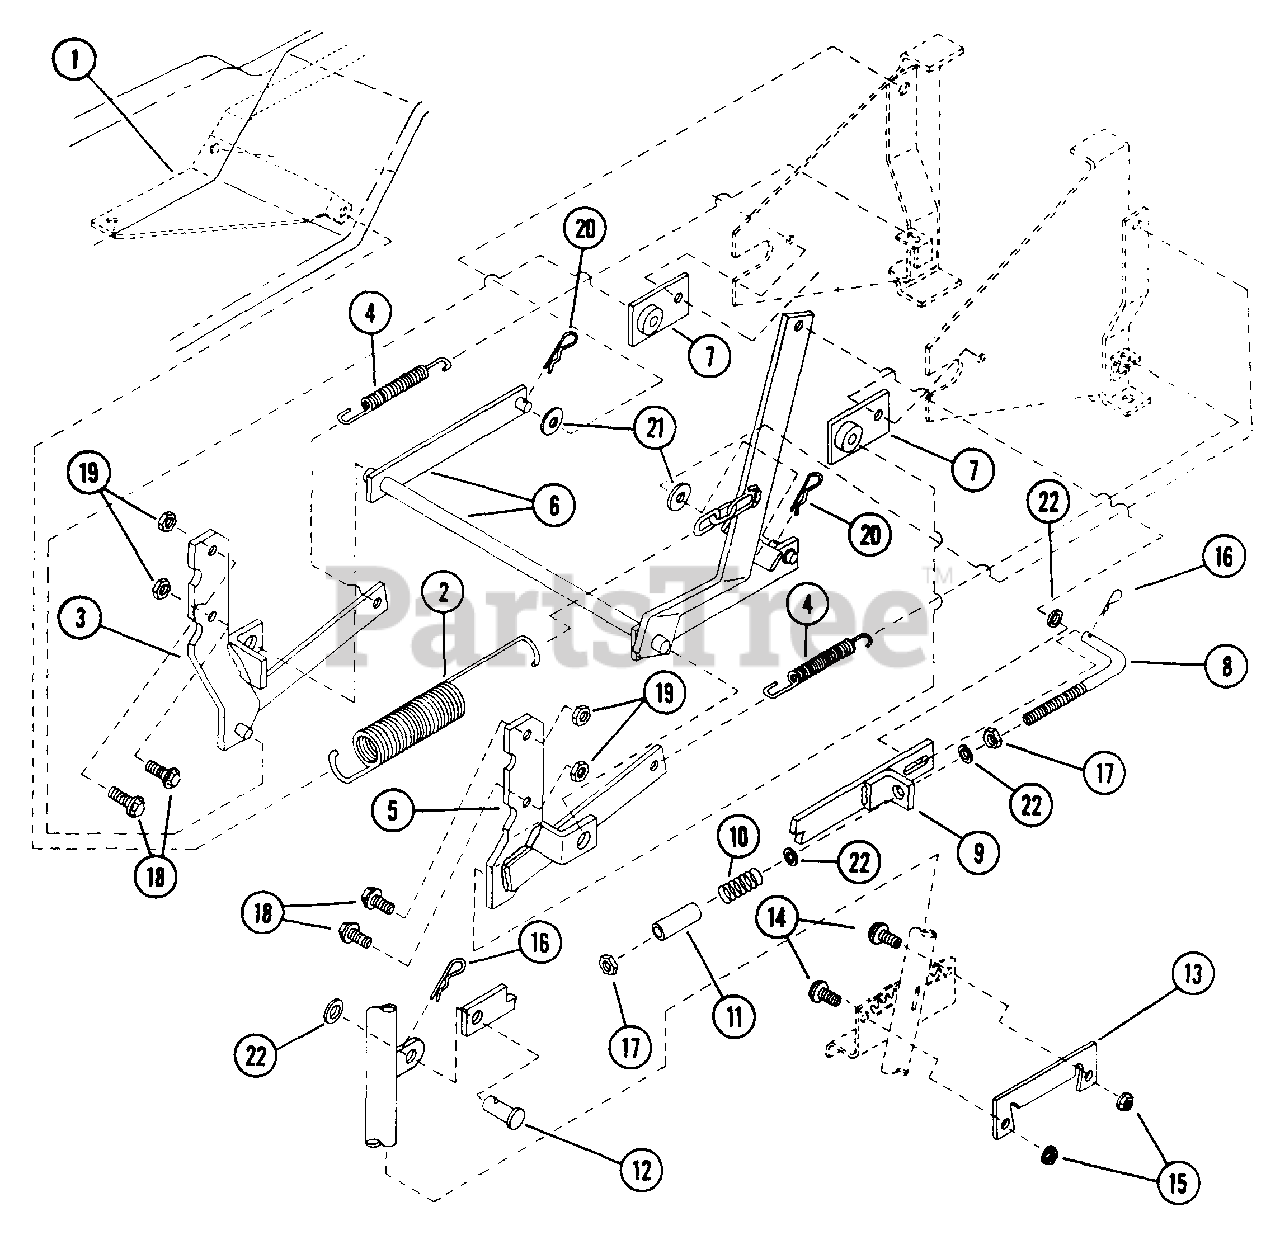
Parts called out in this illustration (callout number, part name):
1	BRACKET, Spring Attaching
2	SPRING, Lift Assist
3	ARM, Left Hand Support
5	ARM, Right Hand Support
6	LIFT-LEVER Structure
7	PIVOT (Structure)
8	ADJUSTER
9	LIFT BAR
11	SPACER
12	PIN, 3/8 x 1 1/16" Clevis
13	PLATE, Lockout (Quadrant)
14	CARRIAGE BOLT, 1/4-20x5/8
15	LOCKNUT, 1/4-20 Hex Flange
16	COTTER HAIRPIN, 1.43 Long
17	NUT, 3/8-16 Hex
18	LOCK-BOLT, 3/8-16x1-1/4 Hex
19	LOCKNUT, 3/8-16 Hex Flange
20	COTTER HAIRPIN
21	WASHER, 1/2 SAE (Flat)
22	WASHER, 3/8 SAE (Flat)
